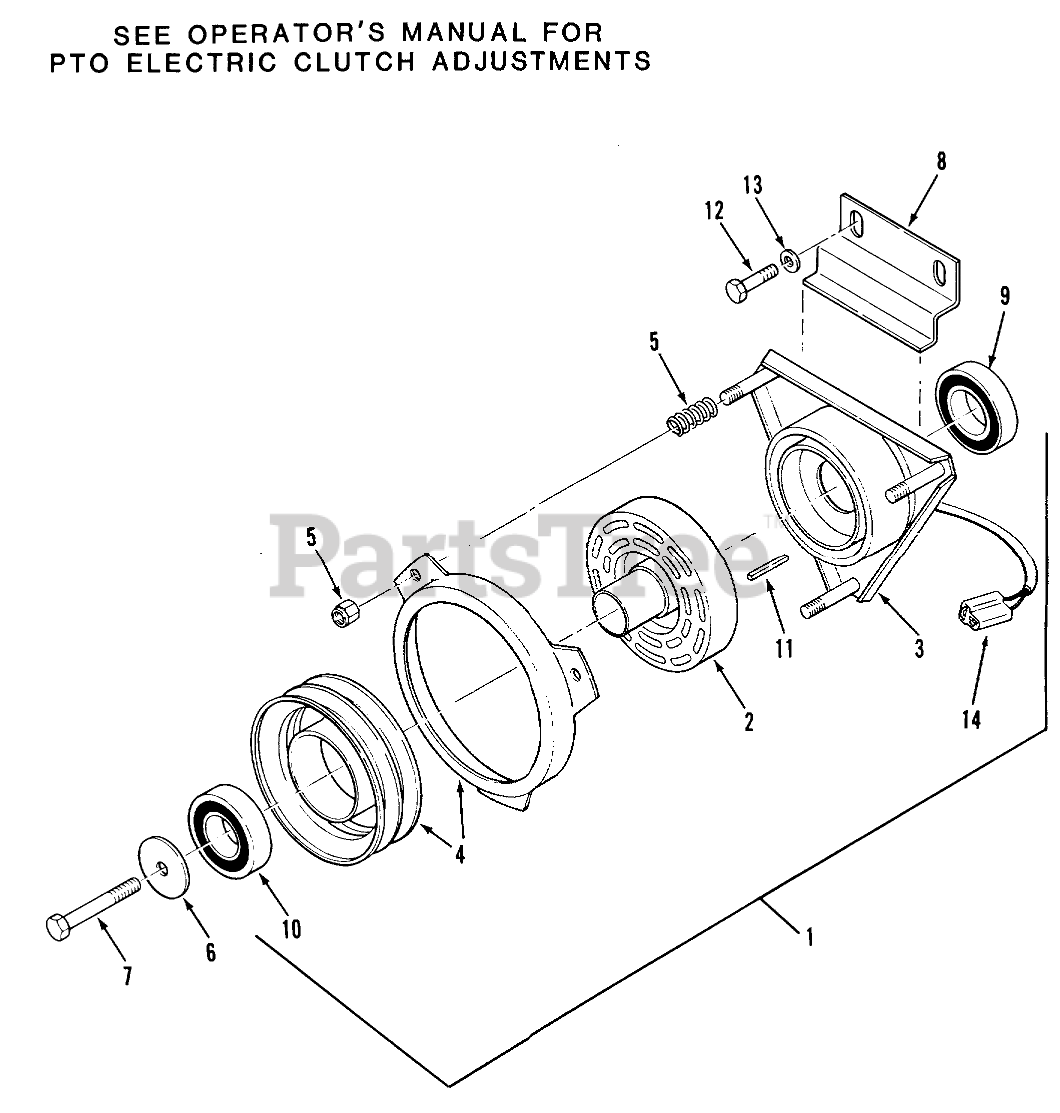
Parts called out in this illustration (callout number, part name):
1	Electric Clutch Complete (includes items 2, 3, 4, 5, 9, 10 & 14)
2	Rotor
3	Field (includes item 9)
4	Armature and Pulley (includes item 10)
5	Spring & Nuts
6	RETAINER-BEARING
7	Bolt 3/8-24 x -1/4
8	BRACKET-CLUTCH B
9	BEARING-FIELD ASS'Y
10	Bearing
11	KEY-SQUARE
12	Bolt
13	Washer
14	CONNECTOR BODY B
